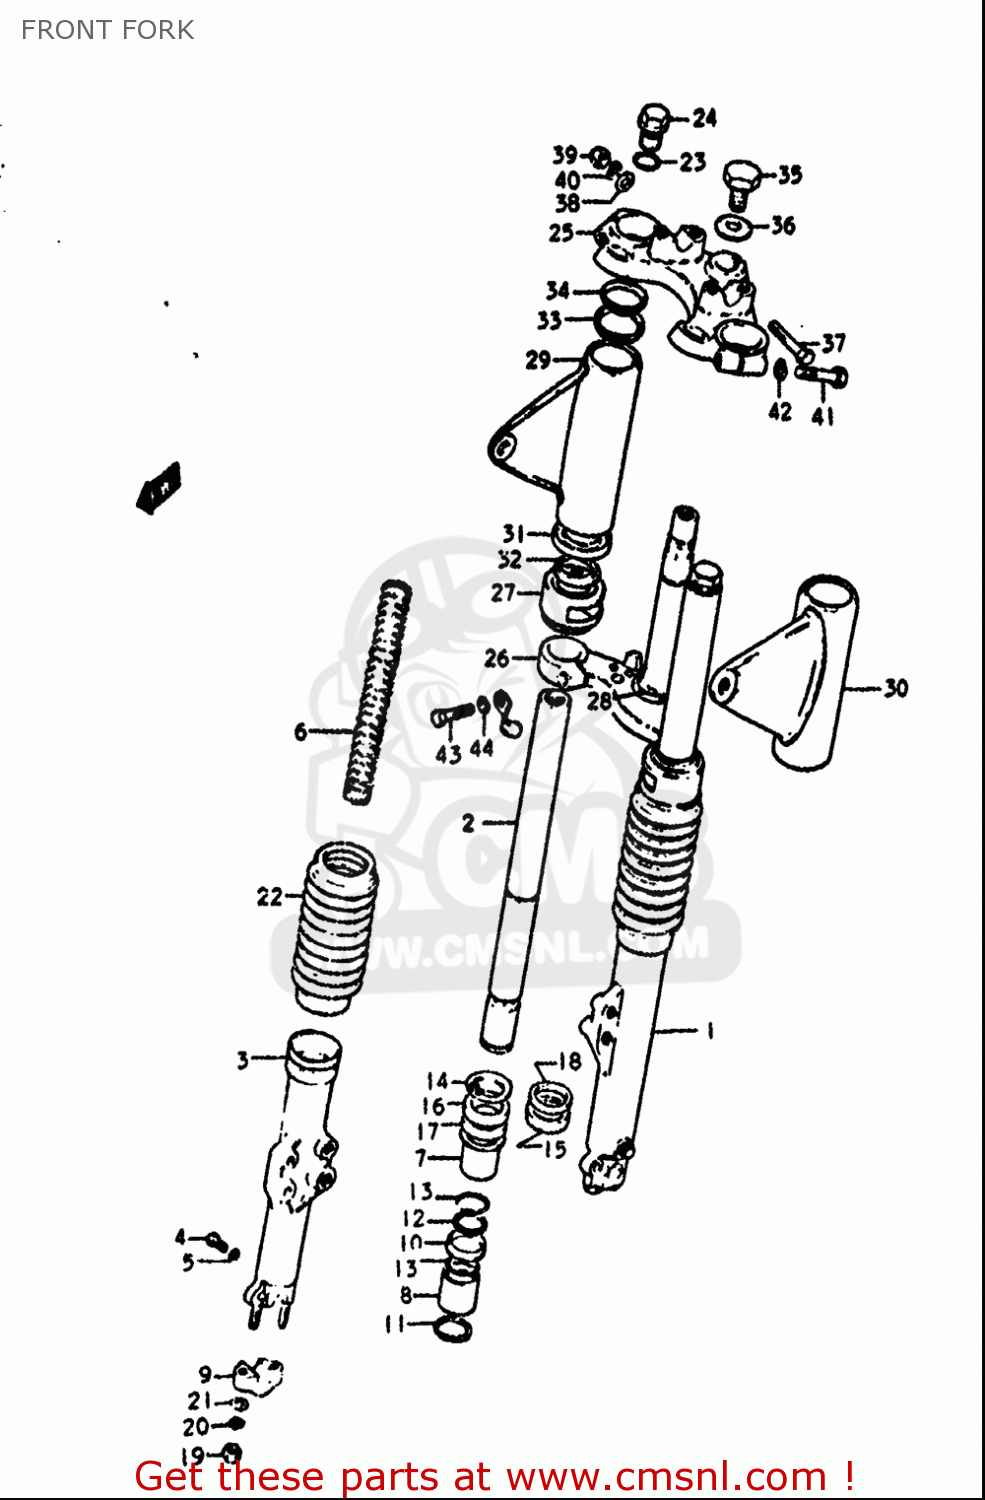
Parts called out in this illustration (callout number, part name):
4	BOLT(6X8)
5	GASKET,DRAIN,PLUG (NAS)
9	HOLDER,AXLE
15	SEAL,OIL 35X48X11
16	SEAL,OIL 35X48X11
17	SEAL,OIL 35X48X11
18	RING,FR FORK
19	NUT
20	WASHER,LOCK
21	WASHER
22	BOOT
23	O RING
24	CAP,INNER TUBE
28	RACE,STEERING OUTER LWR
31	GUIDE
32	CUSHION,HEADLAMP BRACKET
33	GUIDE
34	CUSHION,HEADLAMP BRACKET UPR
37	BOLT
38	WASHER
39	NUT
40	WASHER,LOCK
41	BOLT
42	WASHER,LOCK
43	BOLT
44	WASHER,LOCK
